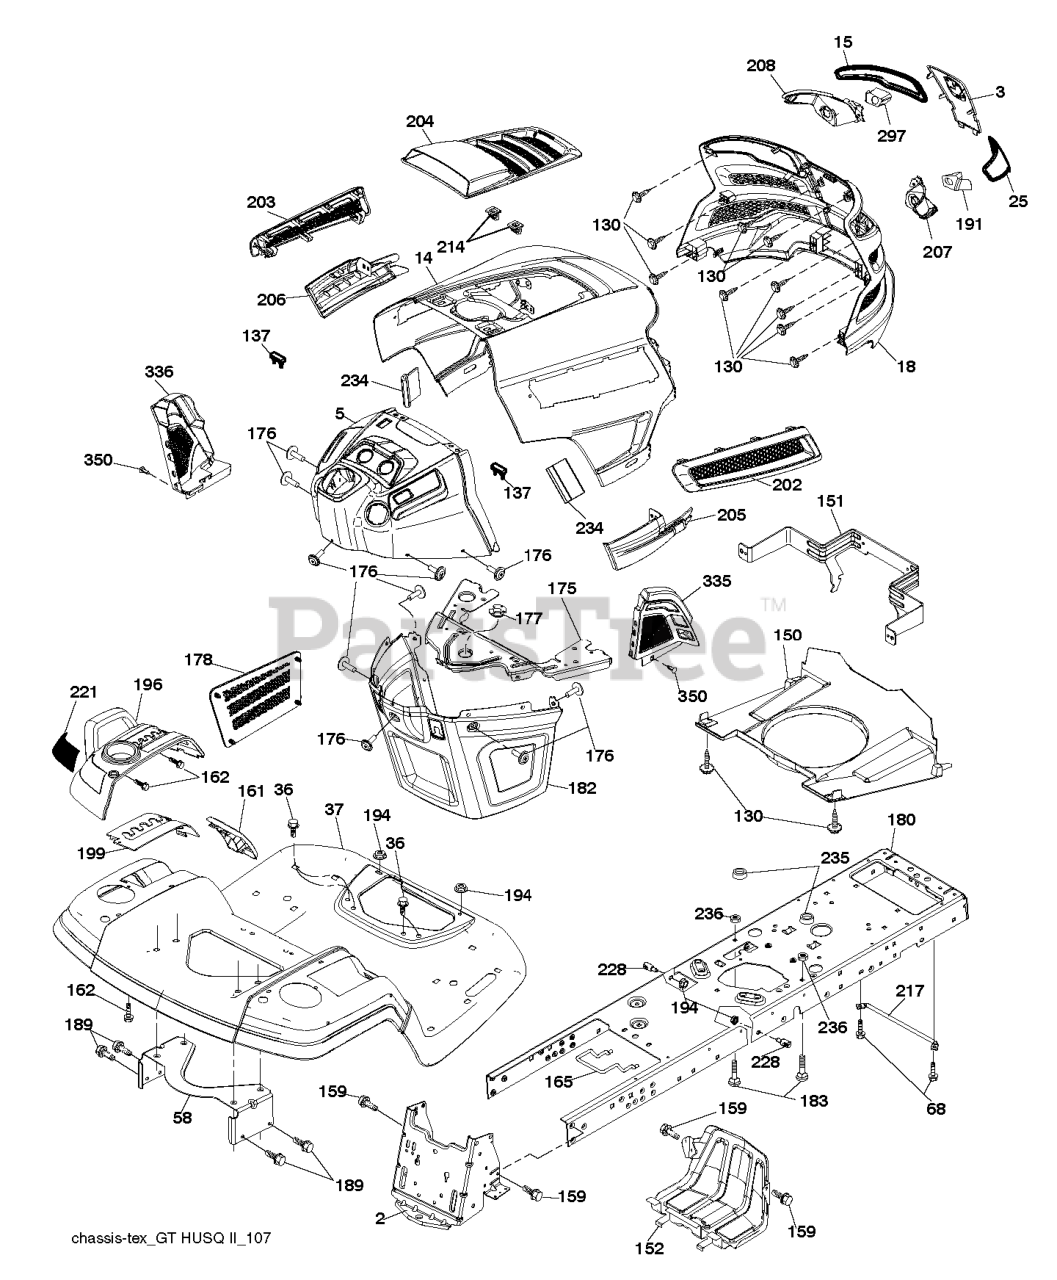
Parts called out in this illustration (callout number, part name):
2	DRAWBAR.STGT
3	APPLIQUE.SUBASM.GT.HUSQ.II
5	DASH.UPP.GT2.DUAL.RD.PTO.MCHOK
14	HOOD.ASM.HUSQVARNA.GT.TEX.422
15	LENS.HEADLIGHT.LH.GTII.2011
18	GRILLE.SUBSTRATE.2011.
25	LENS.HEADLIGHT.RH.GTII.2011
36	SCREW 5/16"
37	FENDER.PNT.TX.GT.CH/FW.ORANGE
58	BRKT.SUPPORT.FNDR/TANK
68	Screw 5/16-18 x 1/2 Hex, Self Tapping 5/16-18 x 1/2
130	SCREW.#10 X 0.750.BOS
137	BUMPER DASH
150	AIR.DUCT.GTV2(2.54"RING HEIGHT
151	BRACKET.PIVOT.HOOD.GT.HUSQ.II
152	SHIELD.BROWNING/DEBRIS
159	SCREW, 3/8-16X3/4
161	CONSOLE.FUEL.WINDOW.HU
162	SCREW.HI-LO.CONSOLE
165	SUPPORT.TANK.REAR.B/TE
175	PLATE.CROSSMEMBER.HUSQ
176	SCREW.#10-24X5/8.RN.QU
177	BUSHING, STEERING
178	CARGO.ASM.NET.TXGT.W/C
180	CHASSIS.STAMPING.LT/GT
182	DASH.LOWER.COMMON.12V.ADAPTOR
183	BOLT.5/16-18X1-1/4 FULL THD
189	SCREW
191	INSERT.REFLECTIVE.RH.HUSQ.GTII
194	NUT LOCK HEX FLANGE 5/16-18
196	CONSOLE.ASM.DCKLFT.W/RF.HQ.DLR
199	PLATE.DECK.LIFT.HUSQVARNA.GT
202	VENT.SIDE.RH.GT.HUSQ.II.
203	VENT.SIDE.LH.GT.HUSQ.II.498
204	VENT.TOP.HUSQ.GT2
205	SIDE.TRIM.RH.GT.HUSQ.II
206	SIDE.TRIM.LH.GT.HUSQ.II.GRAY
207	BEZEL LIGHT.RH.GT.II.MYLAR
208	BEZEL LIGHT.LH.GT.II.MYLAR
214	CLIP.RETAINER.TINNER.
217	ROD.PIVOT.HOOD
221	REFLECTOR.LH.TEX GT HU
228	STUD.FASTNER.W/ANTI-ROTATE
234	BUMPER.HOOD.TEX.HUSQVARNA
235	SPACER FENDER
236	NUT.CENTERLOCK.5/16-
297	INSERT.REFLECTIVE.LH.HUSQ.GTII
335	COVER.RH.CLOSE.OUT.BLACK
336	COVER.LH.CLOSE.OUT
350	CLIP.X-MAS.TREE
